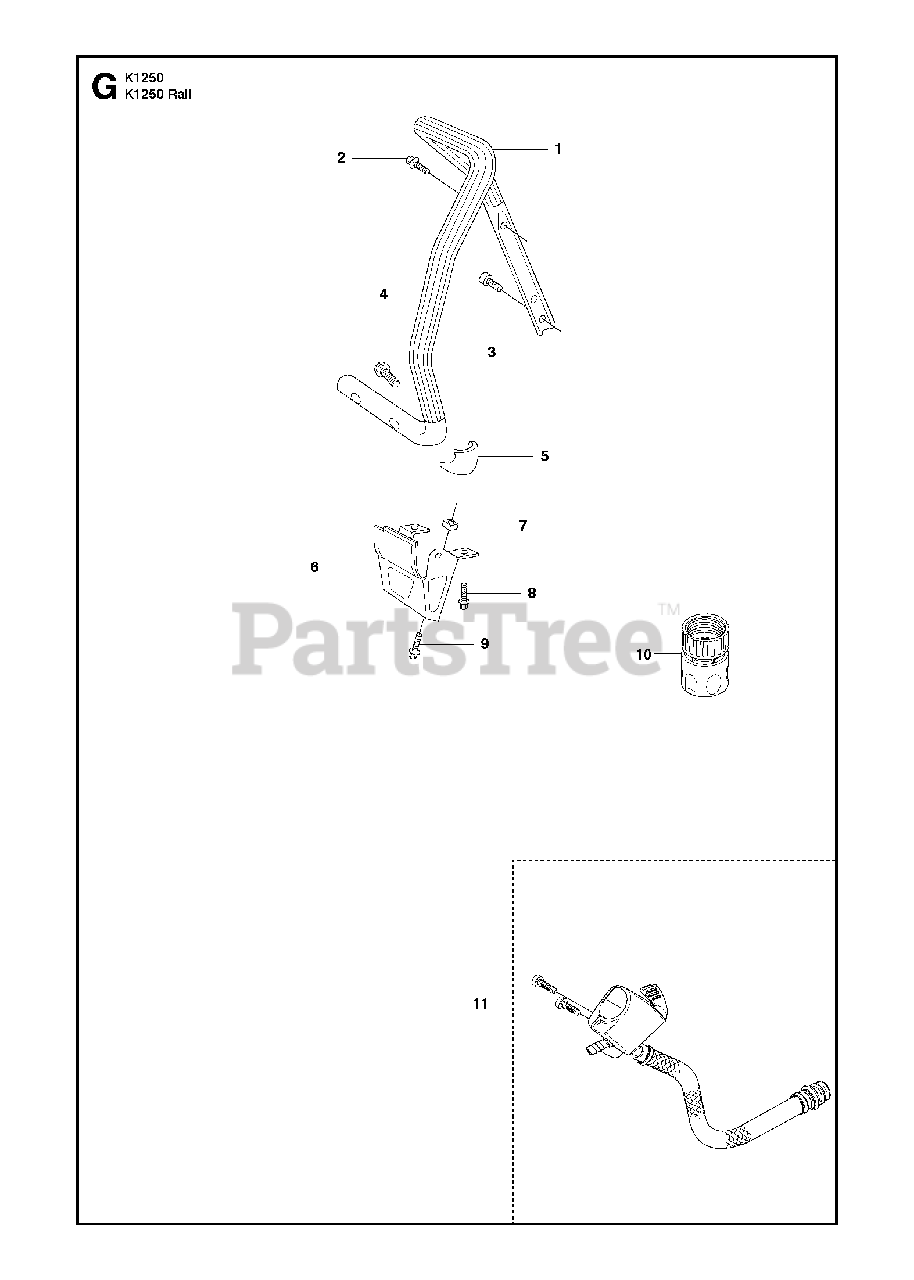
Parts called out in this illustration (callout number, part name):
2	SCREW IHSCFM
6	GROUND SUPPORT
9	SCREW IHSCFM
